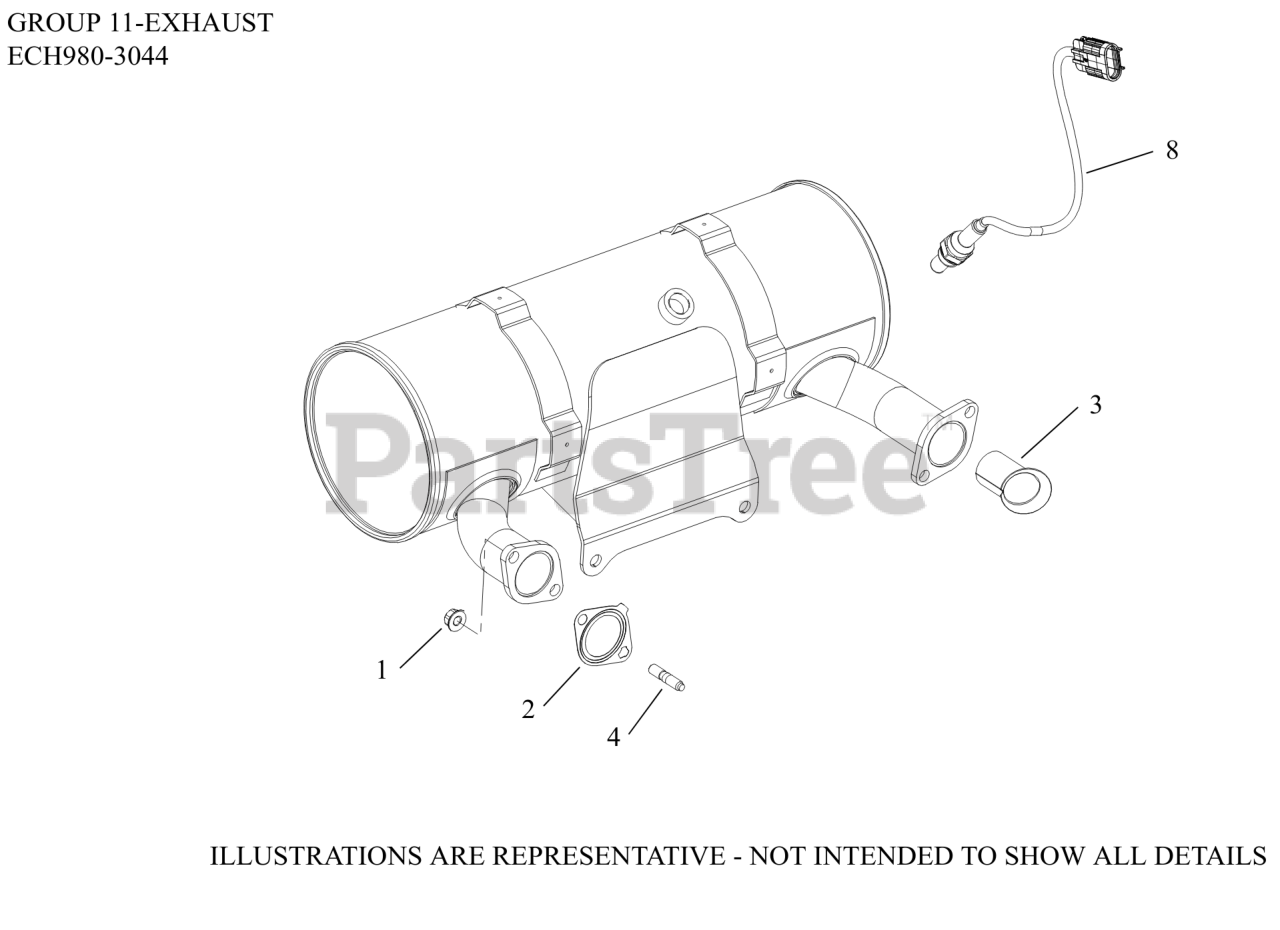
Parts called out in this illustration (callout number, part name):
1	NUT, HEX FLANGE LOCK (M8)
2	GASKET, EXHAUST
3	LINER, EXHAUST PORT
8	SENSOR, OXYGEN (M18 x 1.5 THREADS)
